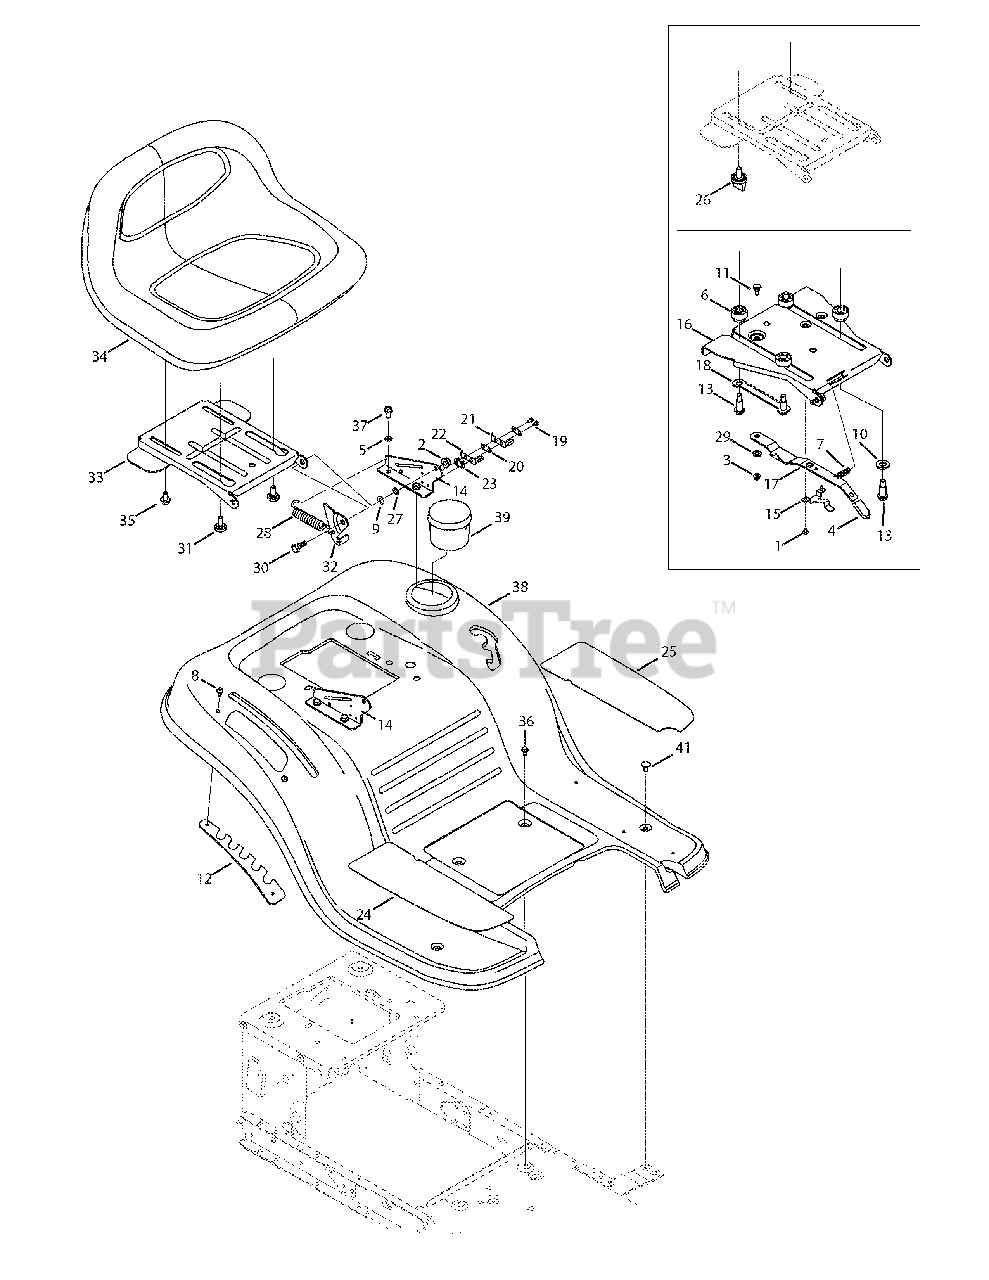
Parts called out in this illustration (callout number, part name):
1	Screw, #10-16, .375
2	Nut, Flange Lock, 5/16-18, GrF
3	Nut, Flange Lock, 1/4-20
4	Seat Adjuster Grip
5	Lock Washer, 5/16
6	Spacer
7	Compression Spring, .41 x 1.5
8	Screw, 1/4-20 x .500
9	Wash, Bell, .340 x .872 x .060
10	Wash, Flat, .531x 1.062 x.134
11	Screw, Shlder, .340 x .285,1/4-20
13	Screw, Shlder, .50 x .925, 3/8-16
15	Seat Stop
18	Seat Adjustment Selector
19	Screw, #8-18 x .50
20	Plate, Insulator
21	Spring Switch, Outer
22	Spring Switch, Inner
23	Plate, Insulator Boss
24	Foot Pad, Abrasive, RH
24	Foot Pad, Rubber RH
25	Foot Pad, Abrasive, LH
25	Foot Pad, Rubber LH
26	Knob, 3/8-16, .875
27	Nut, Speed, .3125 Id
28	Spring, Exten., .84 Dia x 4.6 Lg.
29	Wash, Flat, .344 x .62 x .033
30	Scr., Shlder, .437 x .268, 5/16-18
31	Screw, Shlder, .625 x .175, 3/8-16
32	Lift Bracket, Seat
34	Seat, Low, Black
34	Seat, Medium, Black
34	Seat, Medium, Yellow
35	Screw, 3/8-16, .875
36	Screw, 1/4-20, 0.500
37	Screw, 5/16-18, 0.750
39	Cup Holder
40	Flat Washer, .406 x .875 x .059
41	Carriage Screw, 1/4-20 x .62
